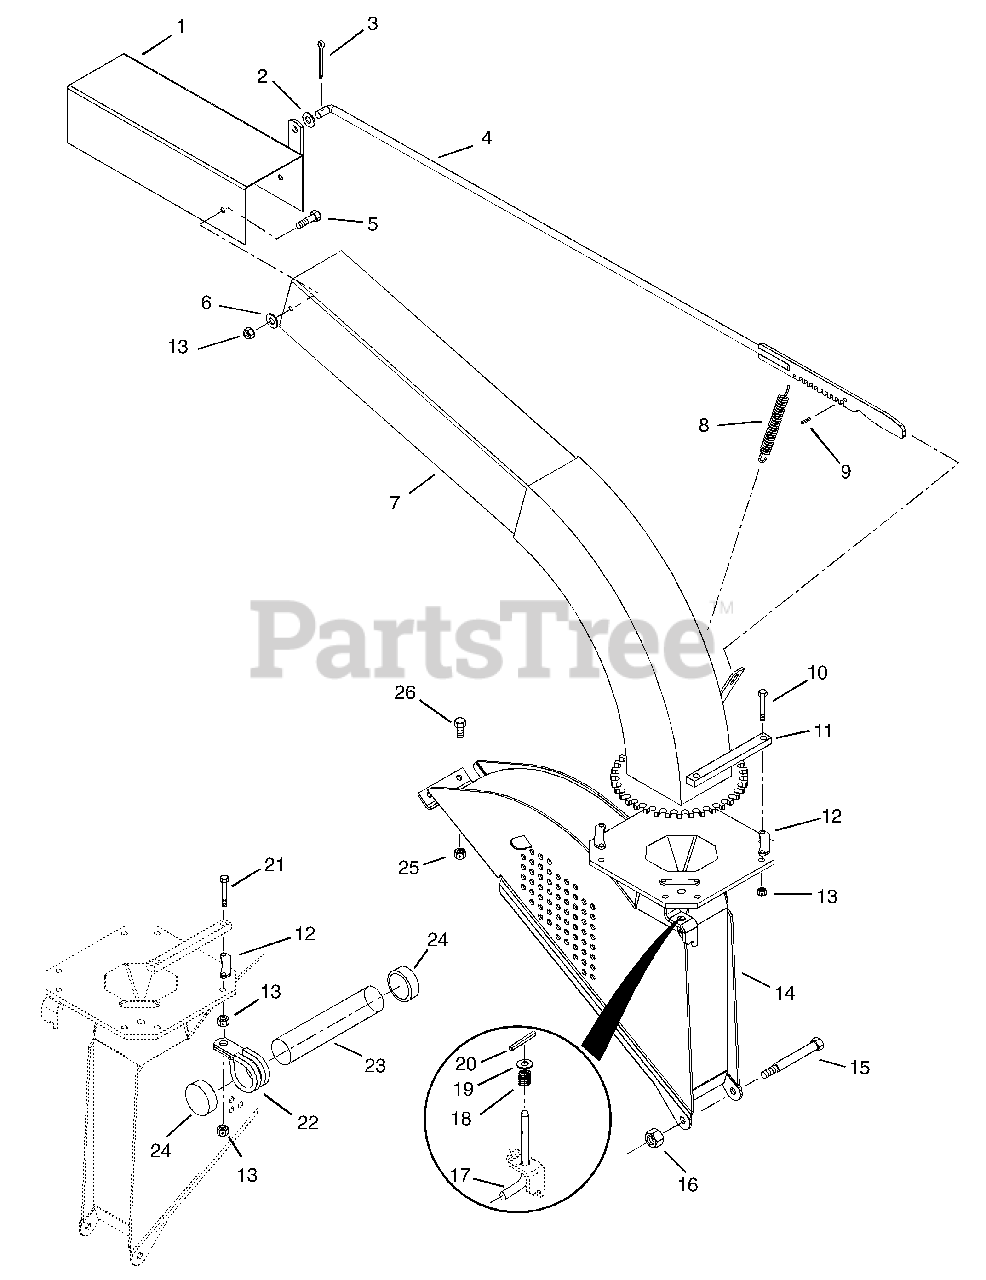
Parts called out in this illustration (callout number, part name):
1	Deflector - Weldment Assembly
2	Washer-Flat-Steel .563 X 1.38 X .109
3	Pin-Center .12 X 1.00
4	Rod-Deflector Control Weldment Assembly
5	Bolt-Hex .38-16 X .75 Grade 5
6	Washer-Flat-Nylon .38 X 1.0 X .083
7	Chute-Discharge Weldment Assembly
8	Spring-Tension .091 X .73 X 5.28
9	Pin-Roll .250 X .750
10	Bolt-Hex .38-16 X 1.75 Grade 5
11	Bar-Discharge Clamp
12	Guide-Discharge Chute
13	Nut-Locking-Center .38-16
14	Cover-Flywheel Housing Assembly
15	Bolt-Hex .50-13 x 6.50 Grade 5
16	Nut-Locking-Center .50-13
17	Pin-Index
18	Spring-Compression .058 x .65 x 2.13
19	Washer-Flat-Steel .531 x 1.06 x .095
20	Pin-Roll .156 x 1.00
21	Bolt-Hex .38-16 X 2.25 Grade 5
22	Clamp 2.00 DIA w/ .406 Hole
23	Plastic Tube-Instructions
24	End Cap-Instruction Tube
25	Nut-Locking-Center .38-16
26	Bolt-Hex .38-16 x .75 Grade 5
